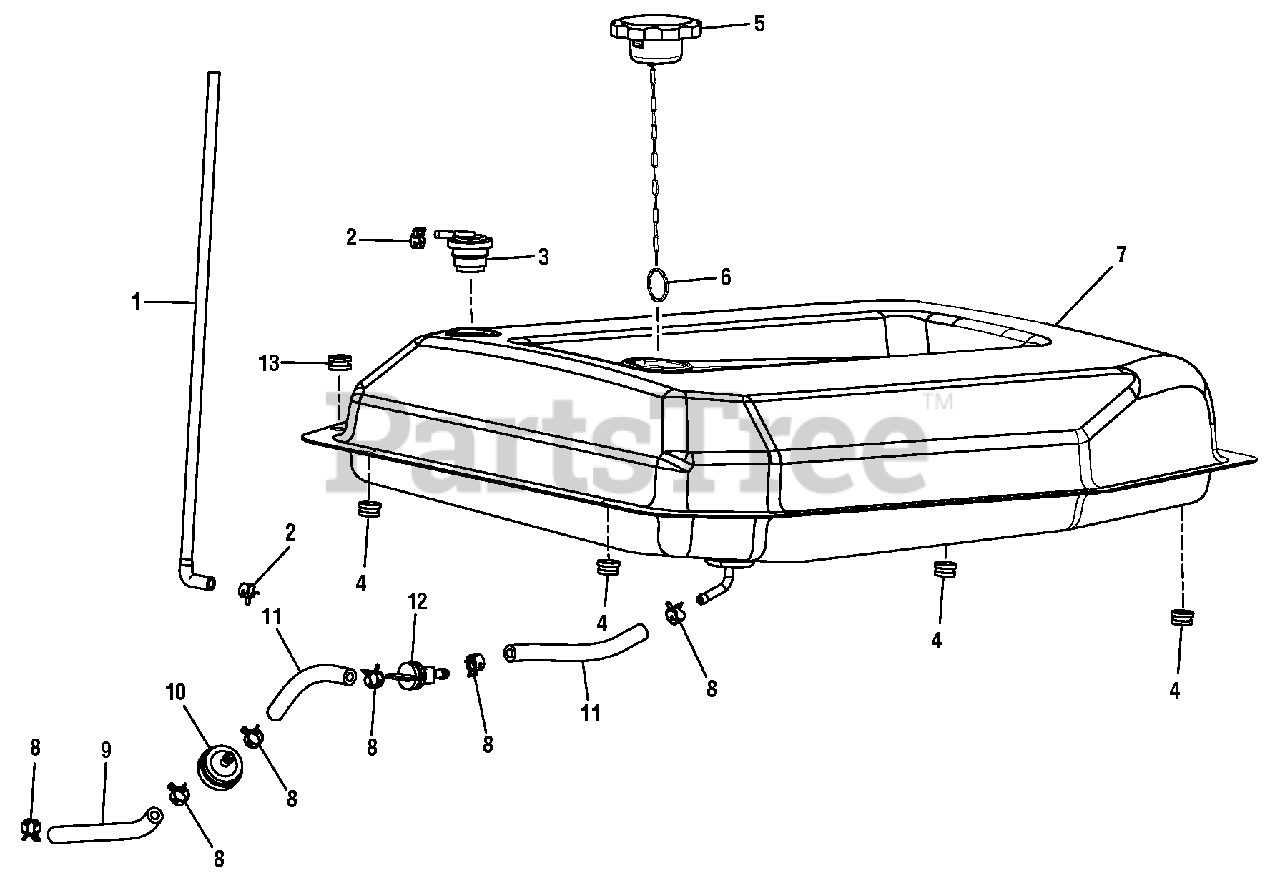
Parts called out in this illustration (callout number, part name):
1	Vapor Hose
2	Clamp (7/16 in.)
3	Fuel Tank Vapor Vent
6	Ring Clip
7	Fuel Tank
8	Clamp (1/2 in.)
9	Fuel Hose
10	Fuel Filter
11	Fuel Hose
12	Fuel Shut Off Valve
